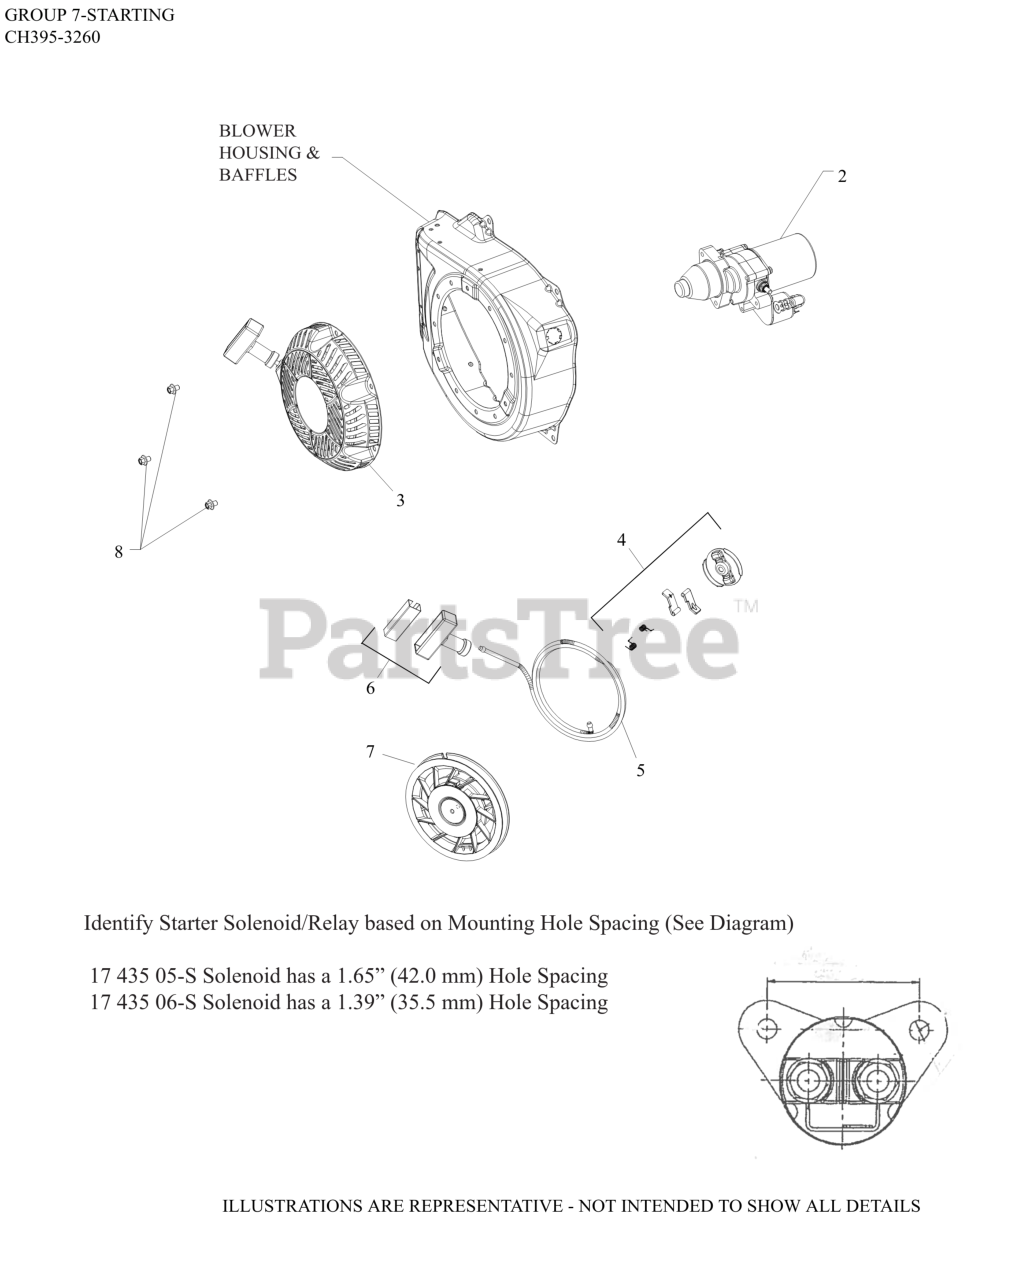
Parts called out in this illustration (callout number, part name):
2	STARTER ASSEMBLY
3	RETRACTABLE STARTER ASSEMBLY
4	KIT, PAWL REPAIR
5	KIT, ROPE
6	KIT, HANDLE
7	PULLEY, RECOIL
8	SCREW, M6 X 8 HEX FLANGE HEAD
